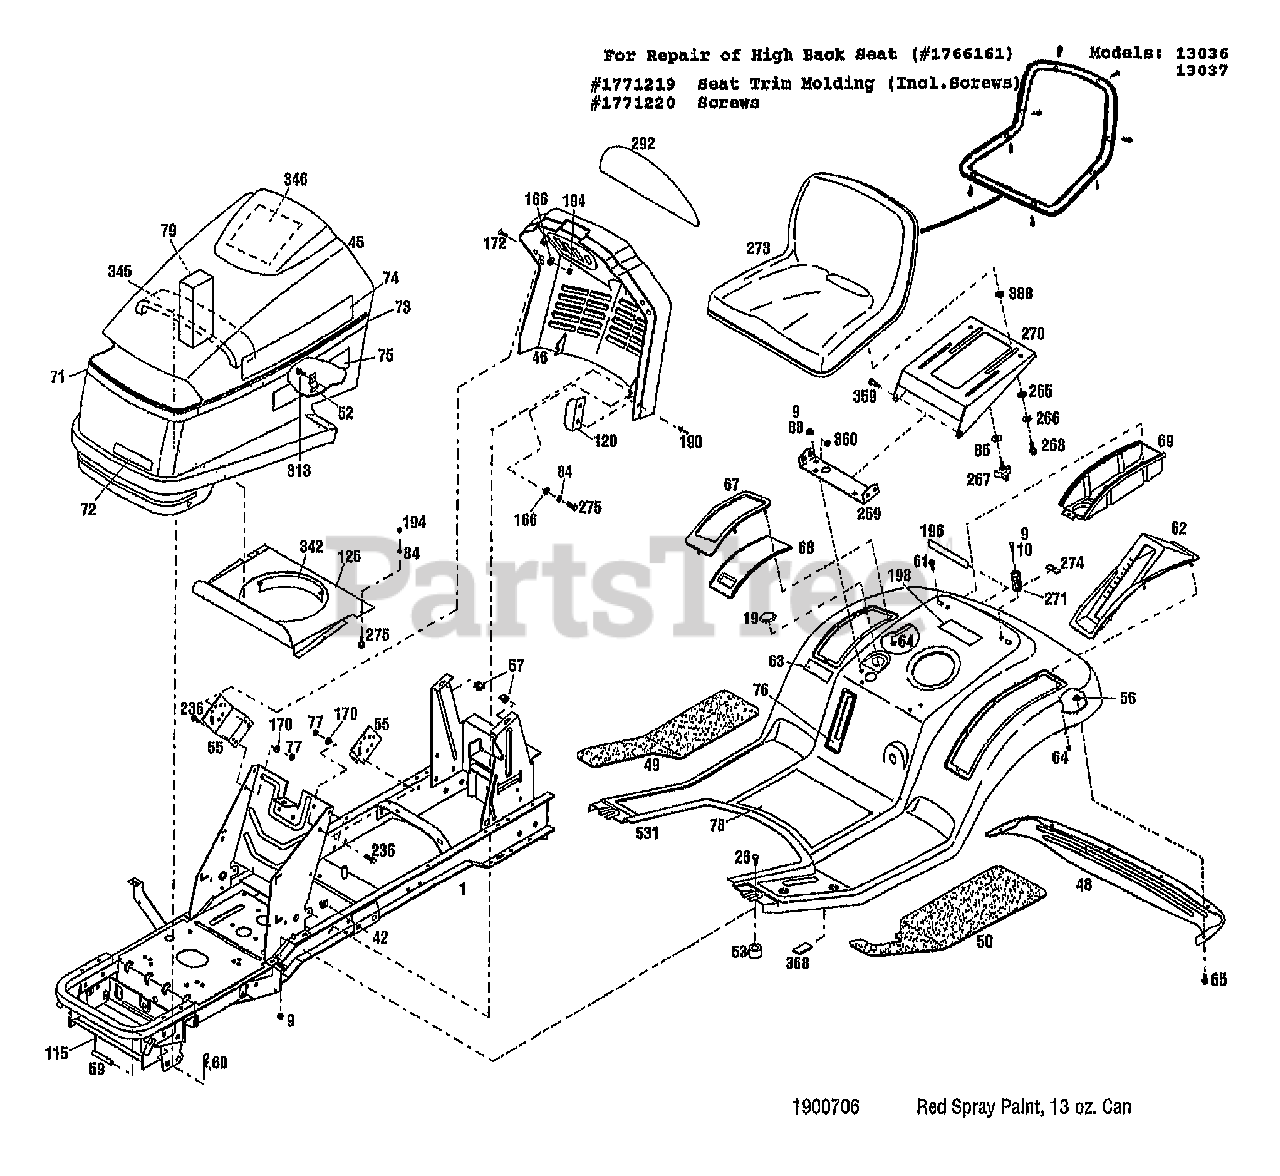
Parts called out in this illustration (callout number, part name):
1	ASSM-FRAME LTX
9	NUT-HFLK 5/16-18 ZP
10	SCR-HHC 5/16-18X.75 GR 5 ZP
19	PLUG 2.50
26	SCR-CARR 5/16-18X1.0 G2 ZP
42	NUT-SPEED
45	HOOD-TRACTOR
46	CONSOLE
48	TRIM-FENDER REAR
49	PAD-FOOT RH
50	PAD-FOOT LH
52	LATCH
53	SPACER-TUBULAR
55	BRKT-MOUNTING
56	NUT-HF/LK 1/4-20 ZP
57	NUT-SELF RETAIN 5/16-18
59	PIN-PIVOT HOOD
60	PIN-HITCH .125X2.56 ZP
61	SCR-LOCK
62	COVER-LIFT HANDLE
63	DECAL-AMERICAN LEGEND-LRG
64	NUT-SELF THREADING
65	SCR-HH 1/4-20X.625
67	TOP-STORAGE COVER
68	COVER-CONTAINER
69	CONTAINER-STORAGE
71	DECAL-STRIPE HOOD FRONT
72	DECAL-LOGO
73	DECAL-STRIPE SIDE
74	DECAL-LOGO TROY-BILT
75	DECAL-MODEL 13035 {13035}
75	DECAL-MODEL 13036 {13036}
75	DECAL-MODEL 13039 {13037}
76	DECAL-FUEL LEVEL
77	NUT-HEX 5/16-18 ZP
78	DECAL-OPER INST
79	BLOCK-SEALING {13037}
84	WASHER-LK .25 ZP
85	WASHER-FLAT 3/8 SAE
88	SCR-CARR 5/16-18X.62 G2 ZP
115	PIN-ROLL .188X1.0
120	BRKT-HOOD ALIGN
125	SHIELD-HEAT UPPER
166	WASHER-FLAT 1.25X.28X.062 ZP
170	WASHER-LK .312 ZP
190	RIVET-POP
194	NUT-HEX 1/4-20 ZP
196	DECAL-LOGO FENDER
198	DECAL-FUEL
236	SCR-HFLK 5/16-18X.75 ZP
265	WASHER-1.06X.51X.09 NYLON
266	WASHER-BOW .74X.52X.01
268	SCR-SHLDR 3/8-16X.25 G5ZP
269	BRKT-SUPPORT SEAT
270	SUPPORT-SEAT
271	SPRING-COMPRESSION
273	KIT-SEAT (TRACTOR) {13035}
273	KIT-SEAT (TRACTOR) {13036/037}
274	BRKT-SPRING HOLD DOWN
275	SCR-HH 1/4-20X.625 G5 ZP
292	LENS-INSTRMTS WARN LIGHTS {13035/036}
292	LENS-INSTRMTS WARN LIGHTS {13037}
342	GASKET-HEAT SHIELD
345	STRIP-SEALING
346	DECAL-SERVICE
359	SCR-HH 3/8-16X.88 G5 ZP
360	NUT-H/LK 3/8-16
388	WASHER-FLAT
531	FENDER-RED W/DECALS
